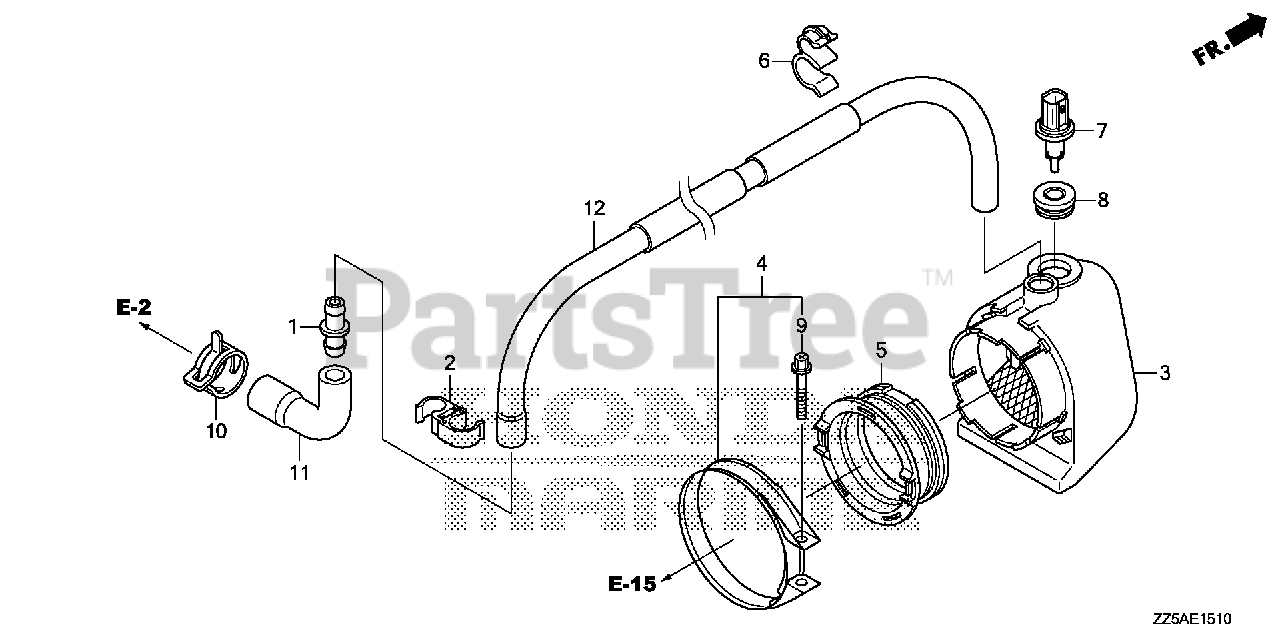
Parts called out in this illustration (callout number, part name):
1	JOINT, HOSE
2	CLAMP A, FUEL TUBE
3	GUIDE, AIR INLET
4	BAND, AIR FLOW
5	GROMMET, AIR GUIDE
6	CLAMP, TUBE (7.5-11.5) (BLACK)
7	SENSOR ASSY., AIR TEMPERATURE (MATSUSHITA DENSHI)
8	GROMMET, TA SENSOR
9	BOLT, CLAMP (4X35)
10	CLAMP, TUBE (D17)
11	TUBE A, BREATHER
12	TUBE B, BREATHER
